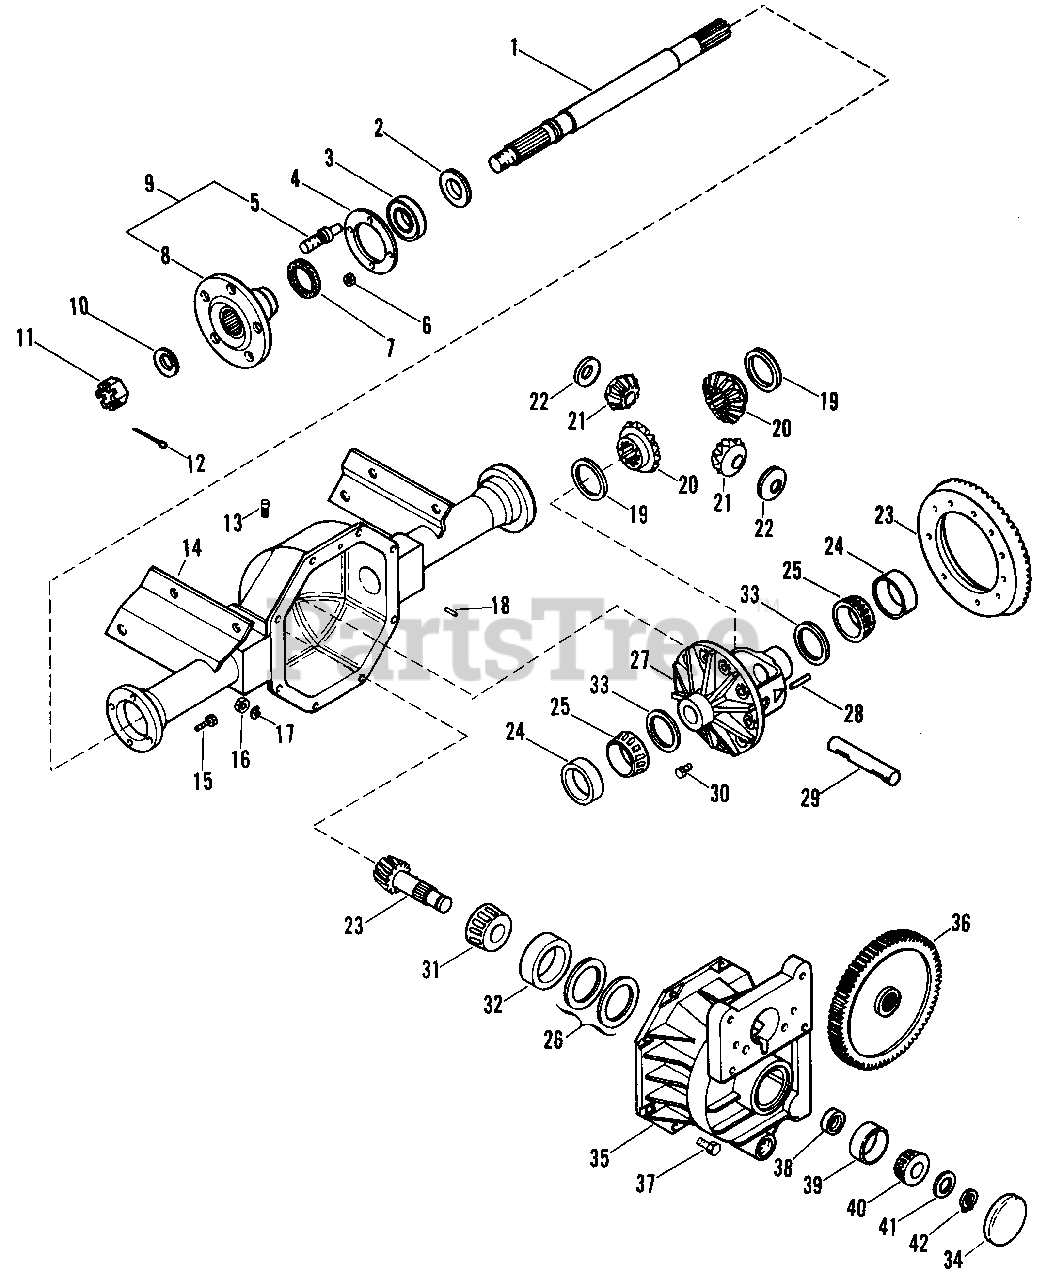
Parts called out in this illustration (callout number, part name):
1	Axle Shaft R.H.
1	Axle Shaft L.H.
2	Oil Seal, 1-3/16 I.D.
3	Bearing, 1-3/16 x 2-9/32
4	Gasket, Wheel Bearing
5	Carrier Lug Bolt
6	Nut, Flange Whizlock 5/16-24
7	Felt Seal
8	Axle Flange
9	Axle Flange Assembly
10	Washer, .890/.905 x 1.500 x .1196
11	Nut, Slotted Hex 7/8-14
12	Pin, Cotter 5/32 x 1.50
13	Vent
14	Lower Housing
15	Screw, Cap 5/16-24 x 1.25
16	Nut, Hex 5/16-18
17	Washer, Lock 5/16 Int Tooth
18	Dowel Pin
19	Washer, 1.578 x 2.375 x .031
20	Side Gear
21	Bevel Gear
22	Washer, Spherical .703 x 1.593 x .031
23	Pinion and Gear
24	Bearing Cup, 2-57/64 O.D.
25	Bearing Cone, 1-5/8 I.D.
26	Shim
27	Differential Case
28	Lock Pin
29	Pinion Shaft
30	Bolt, Special 3/8-24 x 13/16
31	Bearing Cone 1-3/16 I.D.
32	Bearing Cup 2-17/32 O.D.
33	Shim
34	Cup Plug
35	Front Housing w/Bearing Cup
36	Spur Gear
37	Bolt, Hex 5/16-18 x 1.00
38	Front Pinion Bearing Spacer
39	Bearing Cup
40	Bearing Cone 27/32 I.D.
41	Shim
42	Ring, Retaining
